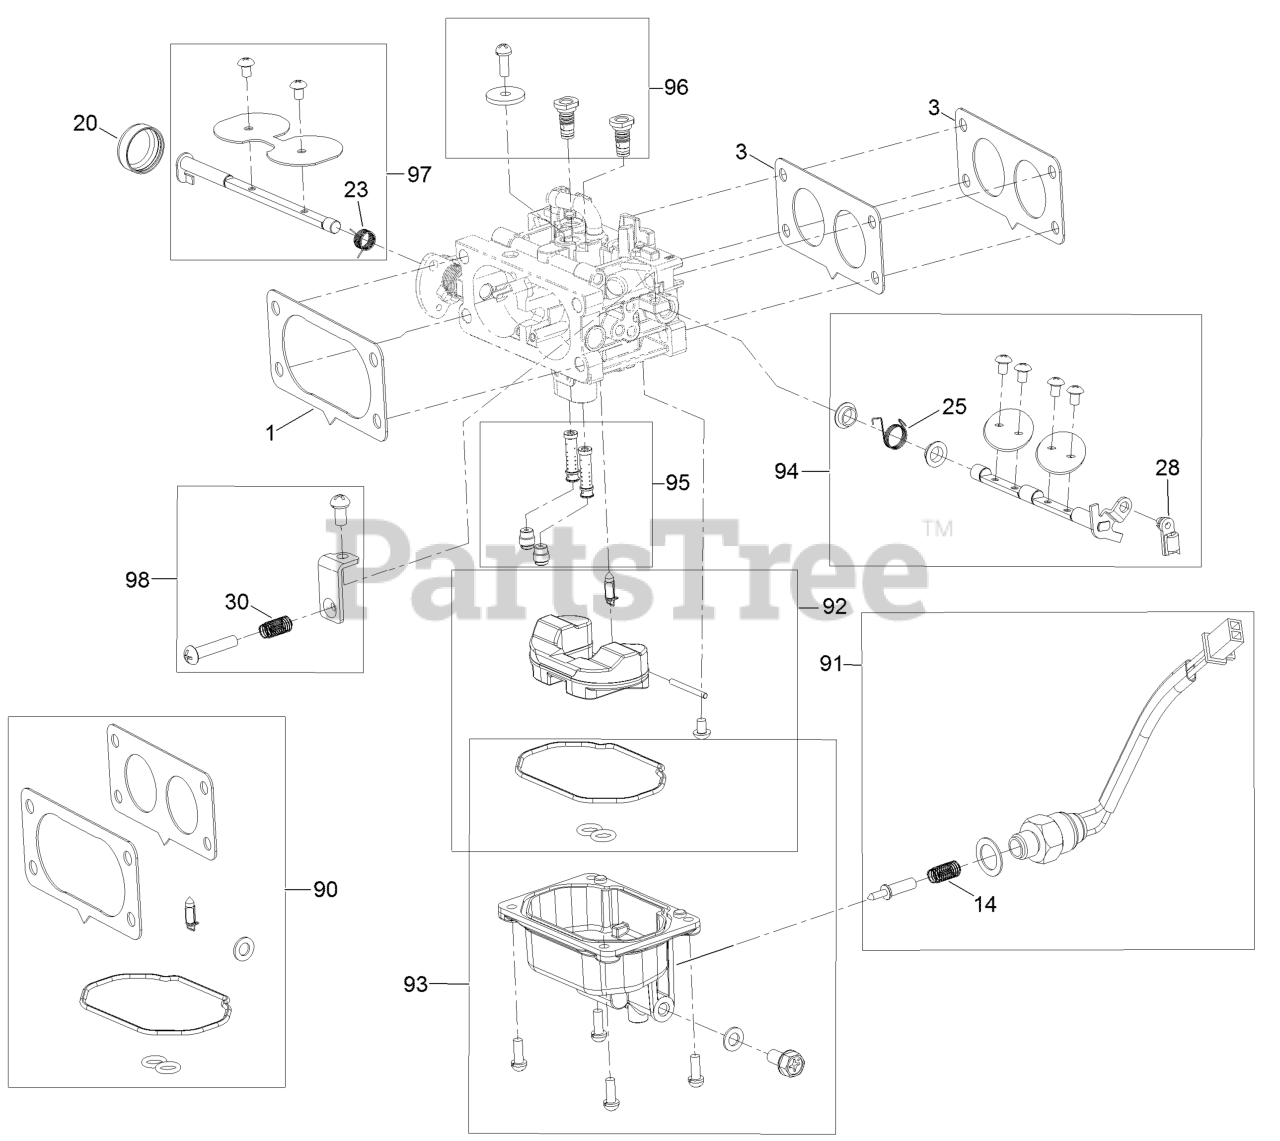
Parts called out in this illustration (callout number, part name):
1	Carburetor
1	GASKET-CARBURETOR
3	GASKET-CARBURETOR
20	COVER-SHAFT, CHOKE
28	CLAMP-LOCK
90	CARBURETOR REPAIR KIT
91	SOLENOID KIT
92	FLOAT KIT
93	BOWL KIT
94	THROTTLE SHAFT KIT
95	NOZZLE AND JET KIT
96	AIR JET KIT
97	CHOKE SHAFT KIT
98	IDLESTOP KIT
